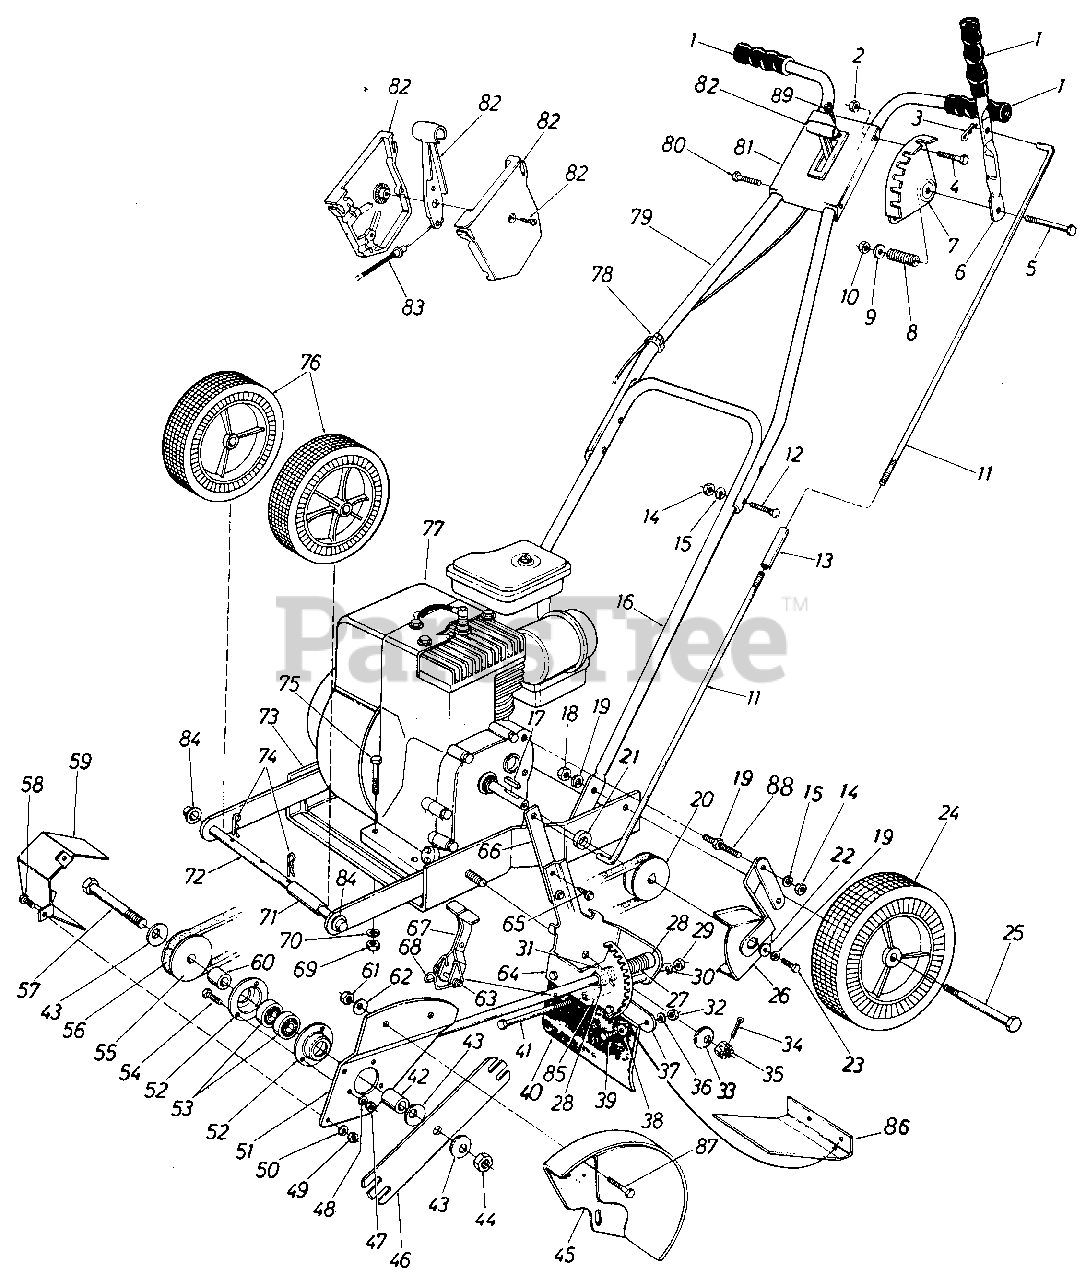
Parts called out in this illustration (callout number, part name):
1	GRIP-BLACK
2	NUT-HEX CENTER L-1/4-20
3	PIN-COTTER-1/8 DIA X 1.00
4	SCREW-HEX 1/4-20 X 1.25
5	SCREW-HEX 5/16-18 X 1.75
8	SPRING
9	WASHER-FL-.344 X .62
10	NUT-HEX CENTER L-5/16-18
11	ROD-CLUTCH
12	BOLT-CARRIAGE 1/4-20 X 1.25
13	ROD-CONNECTING
14	NUT-HEX 1/4-20
15	LOCK WASHER 1/4 DIA
16	HANDLE-LOWER
17	KEY-SQ 3/16 X .75
18	NUT-HEX 3/8-16
19	WASHER-LOCK-3/8
20	PULLEY-ENGINE
22	WASHER-FL-.385 X 1.00 X .135
23	BOLT-3/8 NF X 1"GR5
24	WHEEL ASSY
25	SCREW-SHLD .498 DIA X 1.450
26	GUARD-BELT
27	SPRING-COMPRESSION
29	NUT-HEX 5/16-18
30	WASHER-LOCK-5/16
31	PIN-SPRING SPIR 3/16 X 1.00
32	NUT-HEX 1/4-20
33	WASHER-BELL .535 ID X1.50 OD X.052
34	PIN-COTTER-1/8 DIA X 1.00
35	NUT-HEX SLOTTED-1/2-20
36	LOCK WASHER 1/4 DIA
37	BRACKET-FLAP
38	WASHER-FL .283 ID X .749 X .030
39	SCREW-HEX 1/4-20 X .50
41	SCREW-HEX 5/16-18 X 4.50
42	SPACER-.635 ID X .88 OD X 1.03
43	WASHER-BELL
44	NUT-HEX INS L-5/8-18
47	NUT-HEX 1/4-20
48	LOCK WASHER 1/4 DIA
49	NUT-HEX 1/4-20
50	LOCK WASHER 1/4 DIA
53	BEARING-BALL
54	SCREW-HEX 1/4-20 C .62
55	PULLEY
56	BELT-3V-31.2
57	SCREW-HEX 5/8-18X4.5
58	SCREW-HEX 1/4-20 X .50
60	SLEEVE
61	NUT-HEX 5/16-18
62	WASHER-BELL .337 X .867 X .057
63	PIN-COTTER-5/32 DIA X 1.00
68	SPRING-TORSION
69	NUT-HEX 5/16-18
70	WASHER-LOCK-5/16
72	AXLE-EDGER
73	BASE ASSY
74	PIN-INTERN COT-1/2 DIA
75	SCREW-HEX 5/16-18 X 1.50
76	WHEEL ASSY
78	TIE-CABLE
79	HANDLE-UPPER
80	SCREW-HEX 1/4-20 X 1.00
81	PLATE-HDLE SUPPORT
82	CONTROL-THROTTLE
83	WIRE-THROTTLE
88	STUD-1/4-20 X 2.12
89	SCREW-TRUSS TAP
